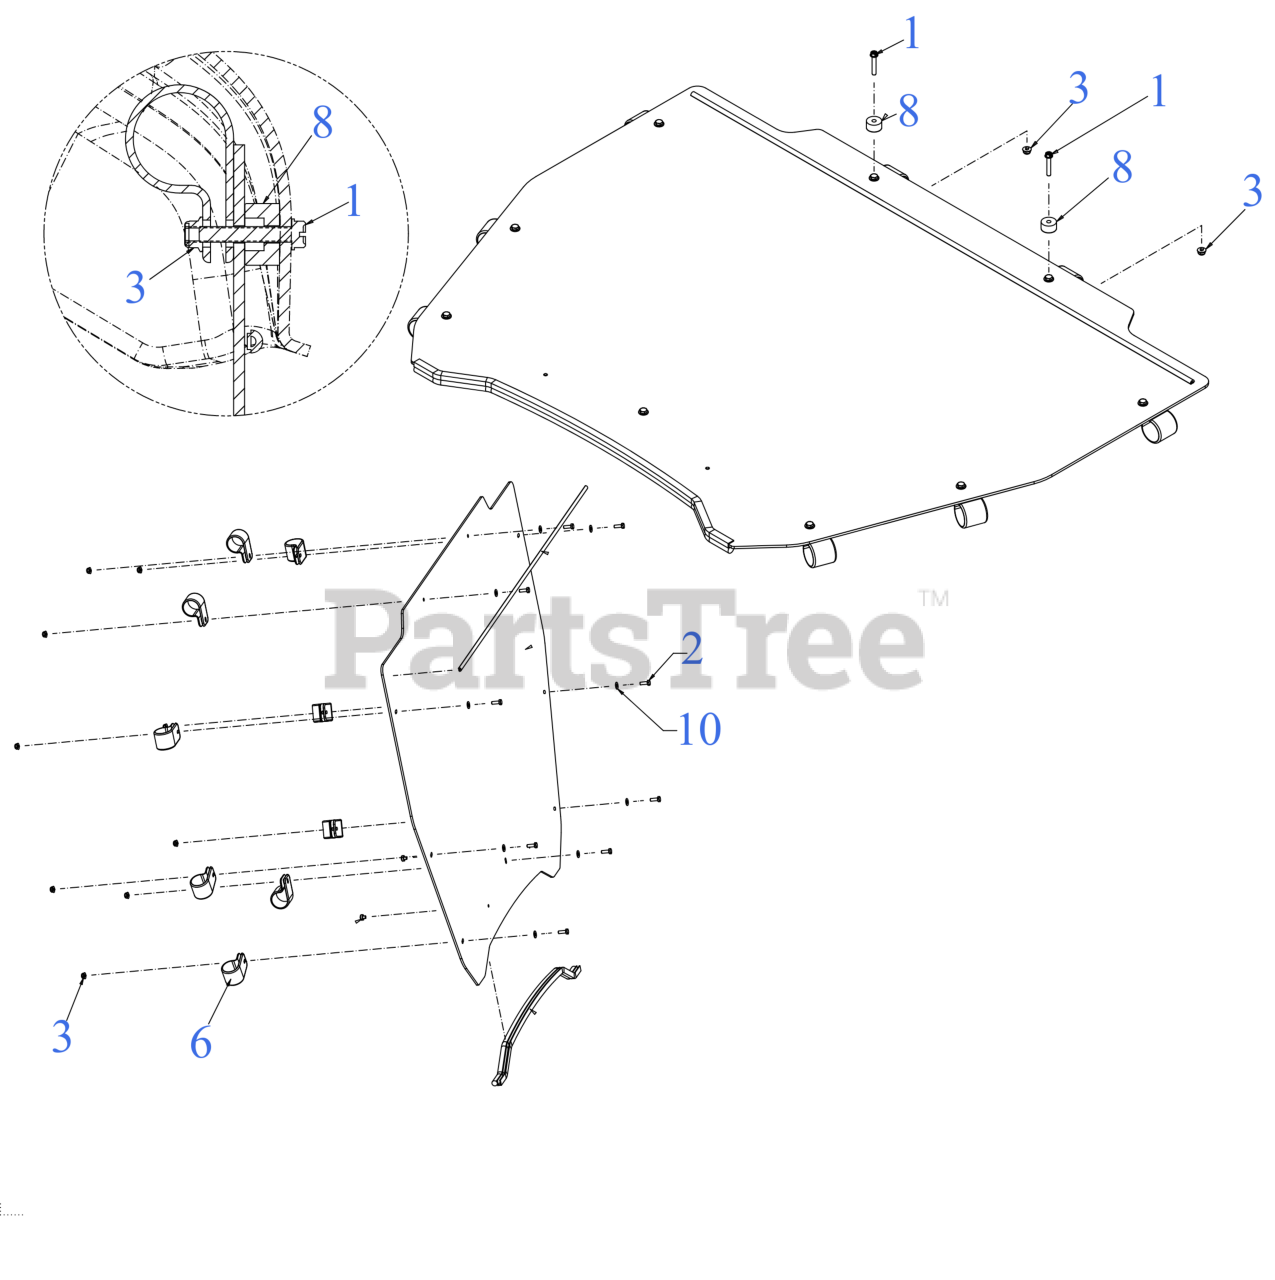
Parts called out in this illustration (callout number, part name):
1	HEX FLANGE BOLT 1/4-20 x 1.5
2	SCREW 1/4-20X.75 GR5
3	FLANGE LOCK NUT
10	FLAT WASHER
